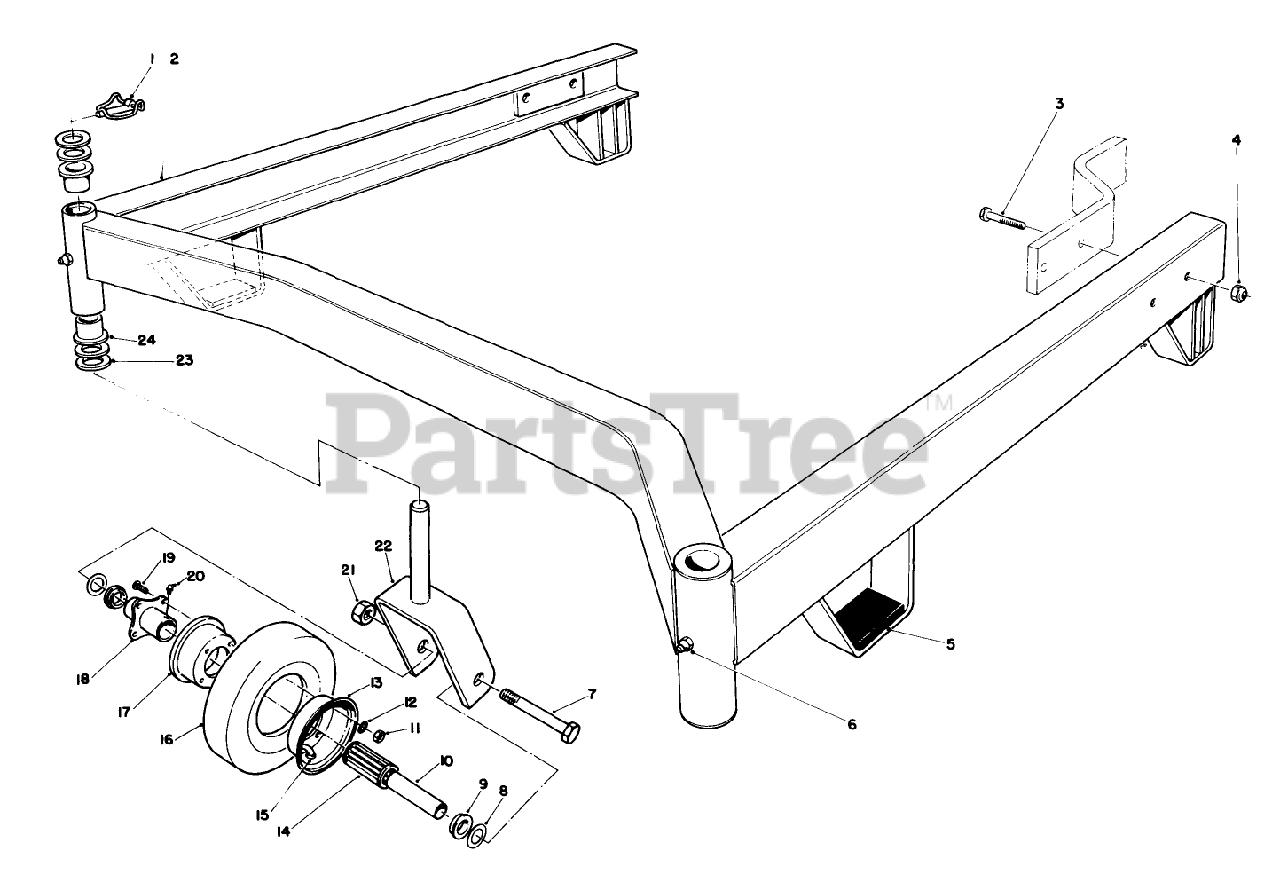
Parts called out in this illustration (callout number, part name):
1	PIN-LYNCH
2	52" Suspension Assembly (Incl. Ref. #23 & 24)
3	SCREW-HH
4	NUT-LOCK, CONE
5	Pad-Rubber
6	FITTING-GREASE
7	SCREW-HH
8	HITCH PLT WA R
9	RETAINER
10	Bushing-Spanner
11	NUT-HEX
12	WASHER-LOCK
13	WHEEL HALF-MALE
14	BEARING-ROLLER
15	Bolt-Stud
16	TIRE-8 Inch (4-PLY)
17	WHEEL HALF-FEMALE
18	HUB-CENTERED
19	WHEEL BOLT
20	FITTING-GREASE
21	NUT-LOCK
22	FORK-Castor
23	WASHER-THRUST
24	Bushing
